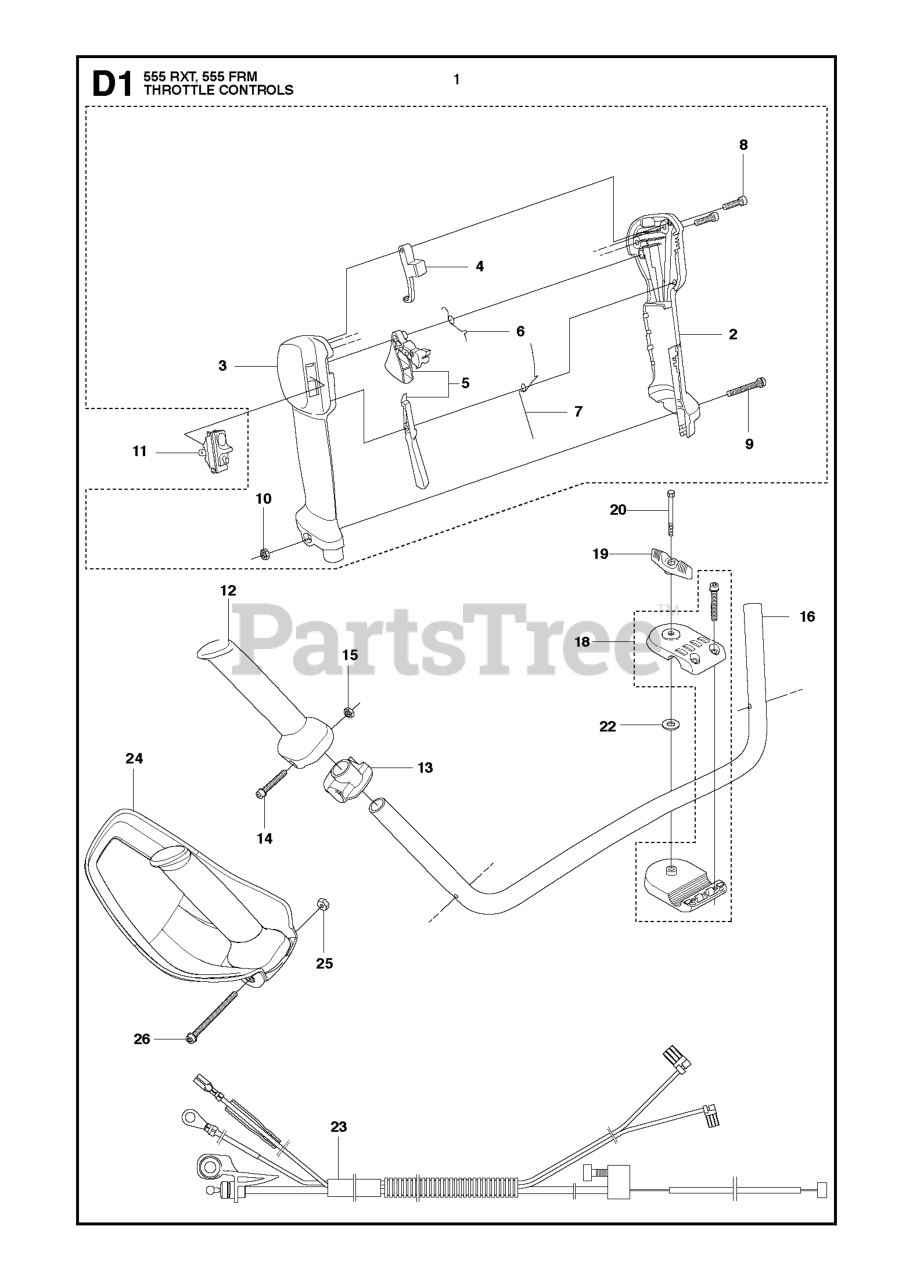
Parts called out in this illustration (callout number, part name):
1	THROTTLE HANDLE ASSY
2	HANDLE HALF RIGHT
3	HANDLE HALF LEFT
4	LOCKOUT STARTER THROTTLE
5	THROTTLE CONTROL
9	SCREW
11	STOP BUTTON
15	NUT M6M M5
18	HANDLEBAR BRACKET KIT
18	HANDLEBAR BRACKET SPARE PART K
23	WIRING
23	WIRING ASSY SKOG
